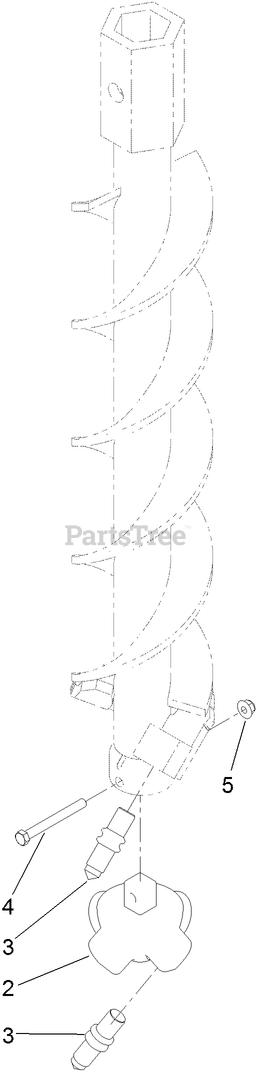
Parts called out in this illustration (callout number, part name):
2	PILOT-AUGER, ROCK
3	TOOTH-BULLET
4	SCREW-HH
5	NUT-HF, NI
